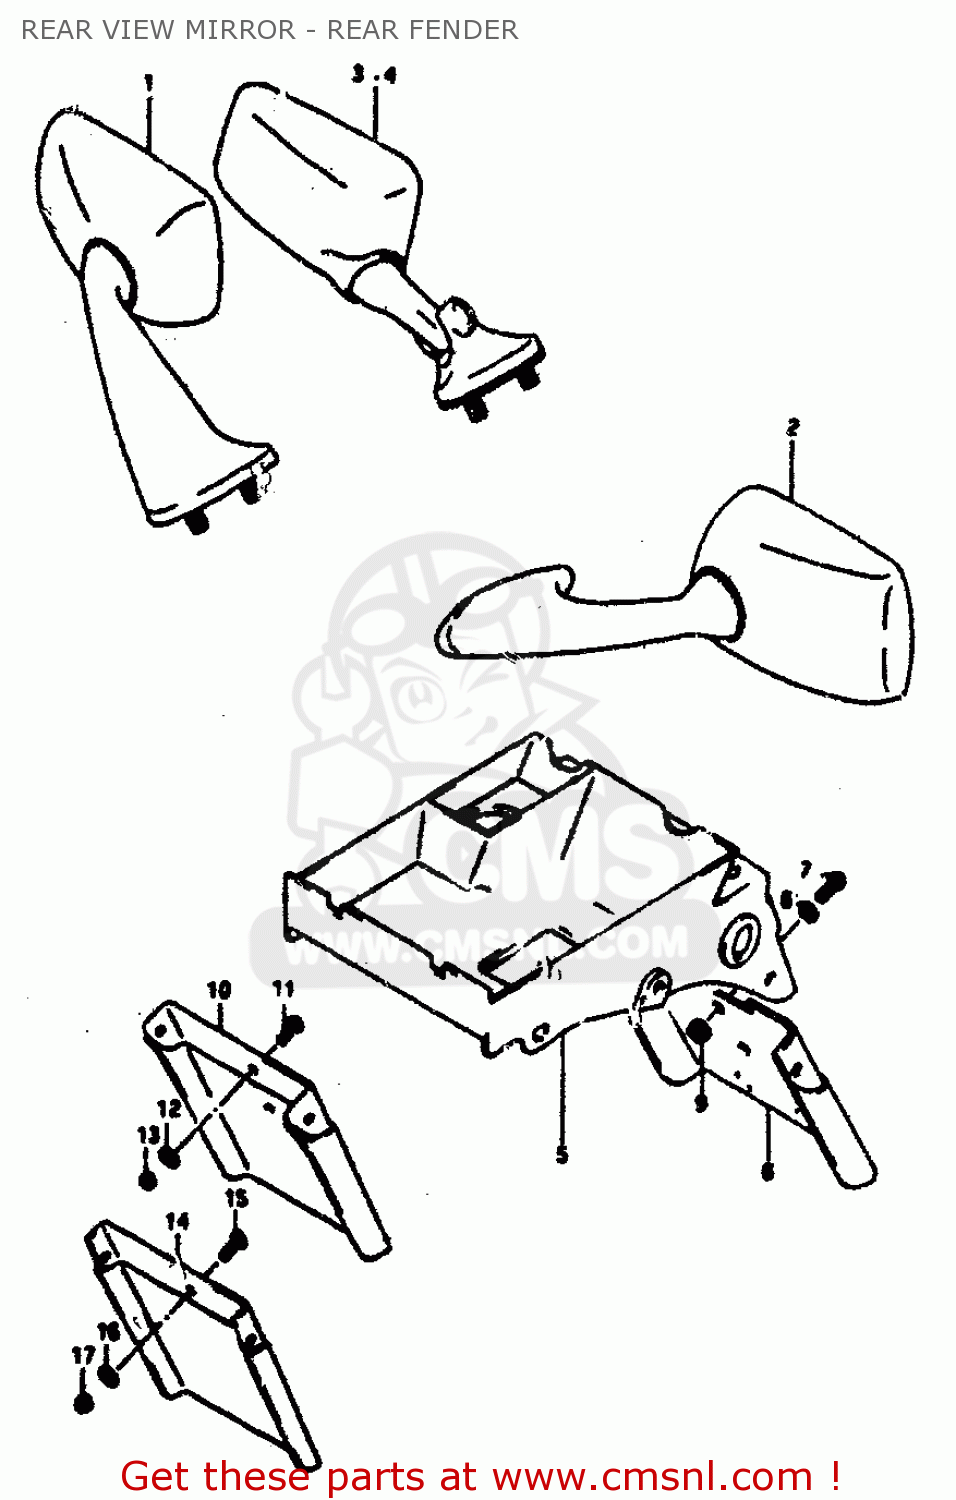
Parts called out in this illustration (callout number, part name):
1	MIRROR ASSY R.
2	MIRROR, L.
3	MIRROR ASSY,RR VIEW,R
4	MIRROR ASSY,RR VIEW,L
5	BODY,RR FENDER RR
6	EXTENSION,RR FENDER
7	SCREW
8	WASHER(6.5X16X1.2)
9	NUT
10	EXTENSION, REAR FENDER
11	SCREW
12	WASHER(6.5X16X1.2)
13	NUT
14	MUD GUARD, REAR FENDER
15	SCREW
16	WASHER(6.5X16X1.2)
17	NUT
